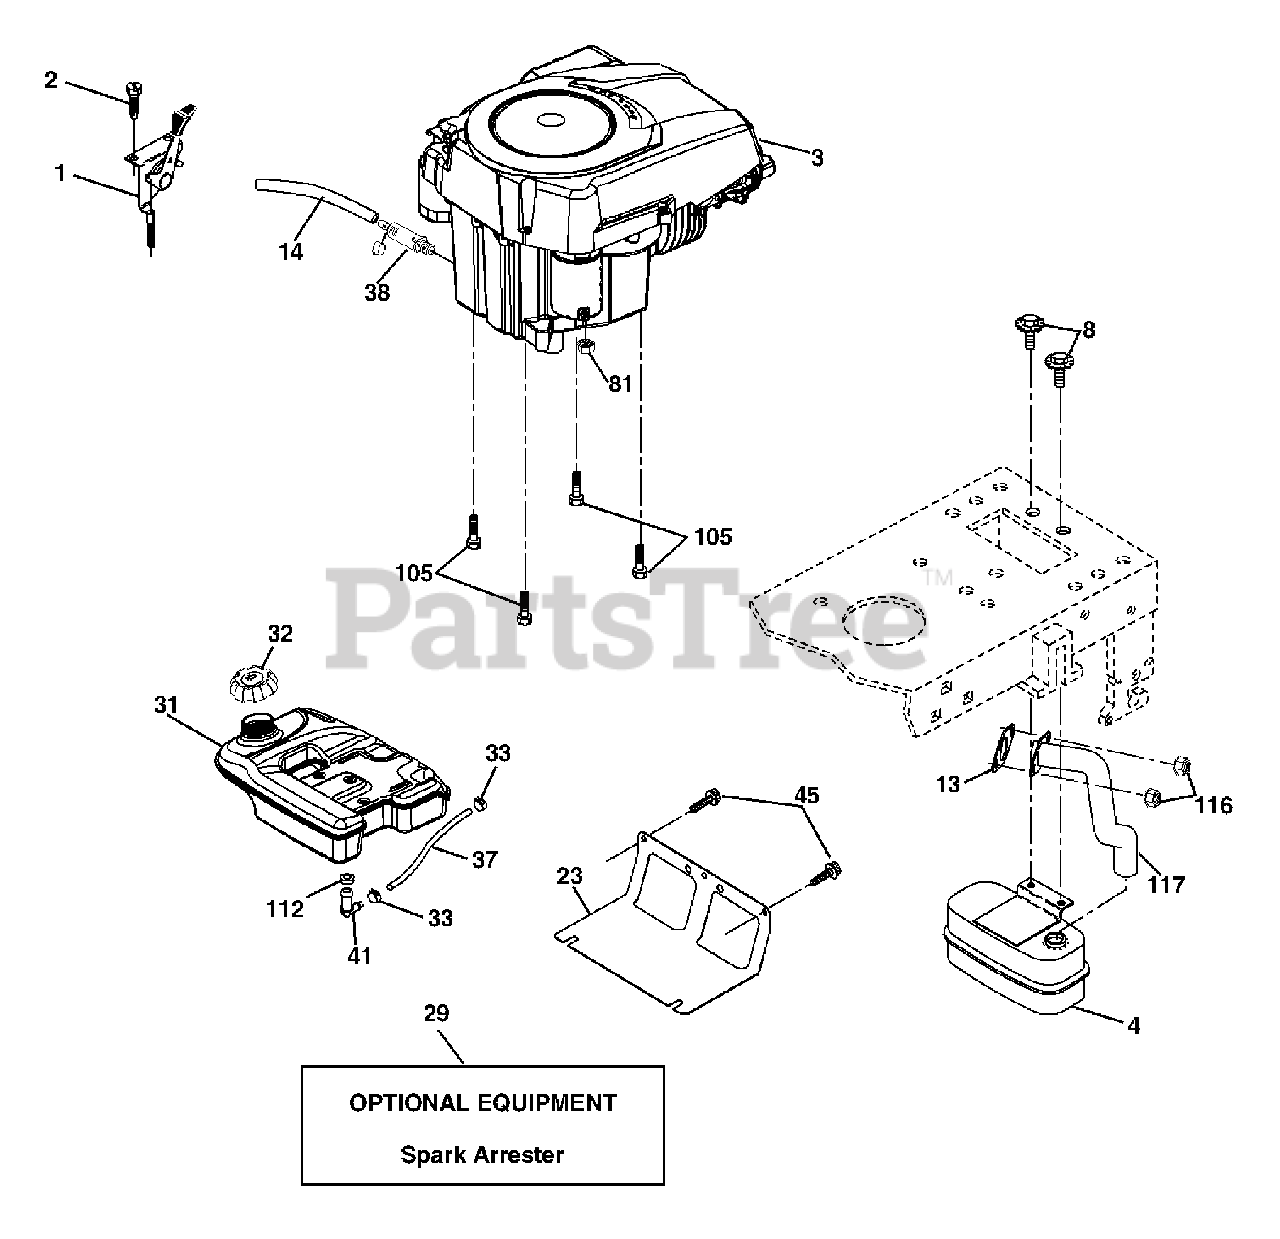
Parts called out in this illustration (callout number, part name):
1	Control, Throttle/Choke
2	Screw Hex Thd Cut 1/4-20 x 1/2
8	Bolt 5/16-18 unc x 3/4 w/Sems
13	Muffler Gasket
14	Tube Oil Drain
23	Shield, Browning/Debris Guard
29	Arrester, Spark
31	Tank, Fuel
32	Cap, Fuel
33	Clamp, Hose Blk
37	Line, Fuel
38	Plug Drain Oil Easy
41	Stem Tank Fuel
45	Screw Hex Wsh Thdrol 3/8-16 x 3/4
81	Nut Keps Hex 1/4-20 unc
105	Screw 3/8-16 x 1
112	Bushing
116	Nut Hex Flange Toplock M8-1.25
117	Exhaust Tube
